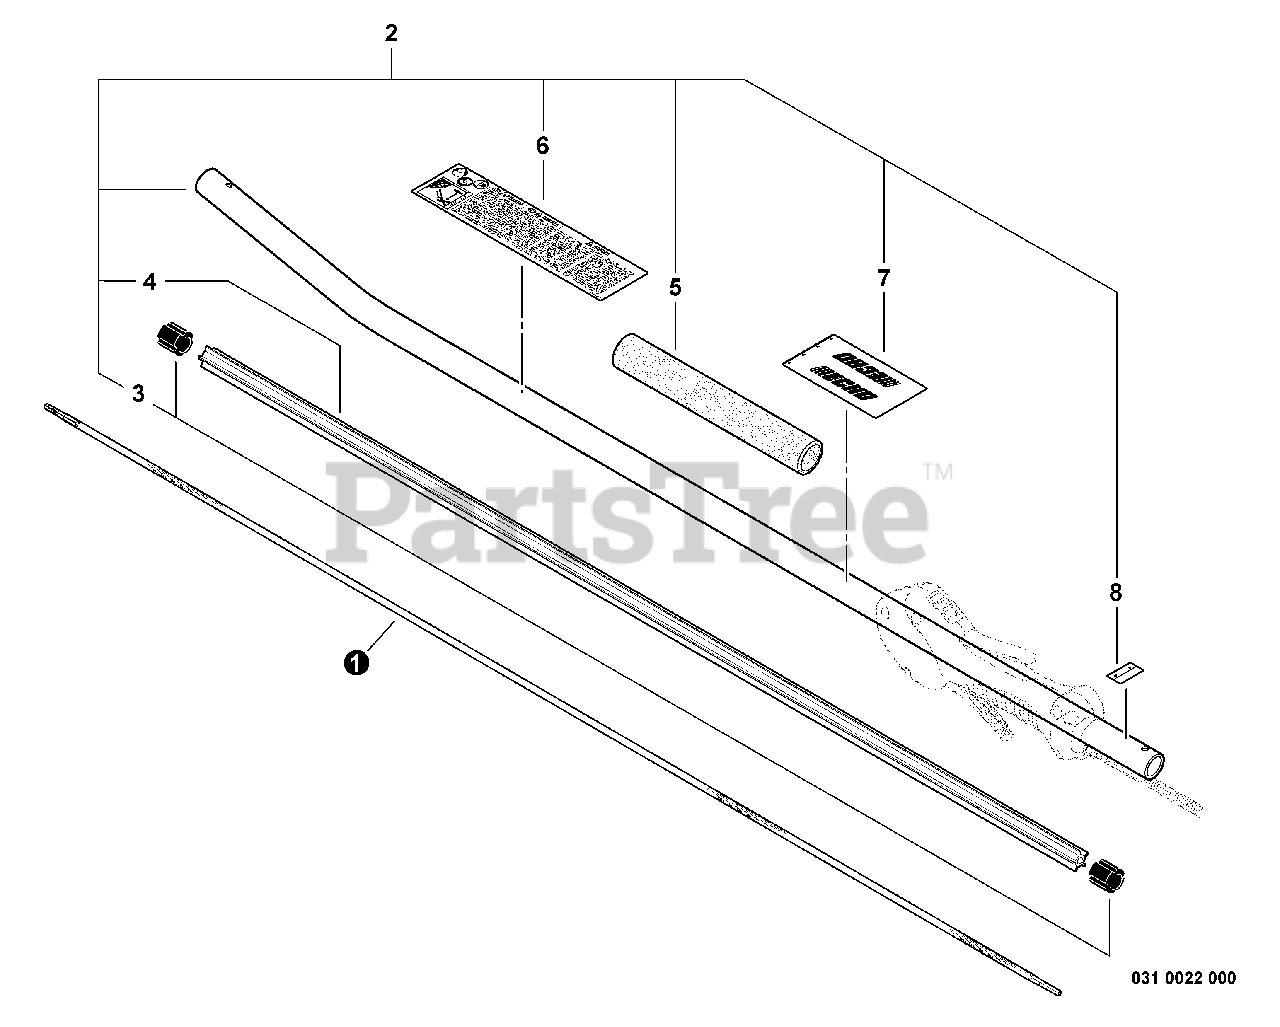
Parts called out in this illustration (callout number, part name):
1	DRIVESHAFT - FLEXIBLE
2	MAIN PIPE ASSY
4	LINER - FLEXIBLE
5	GRIP, HANDLE
6	LABEL, CAUTION
7	LABEL, HANDLE LOCATION
8	LABEL - ALIGNMENT
